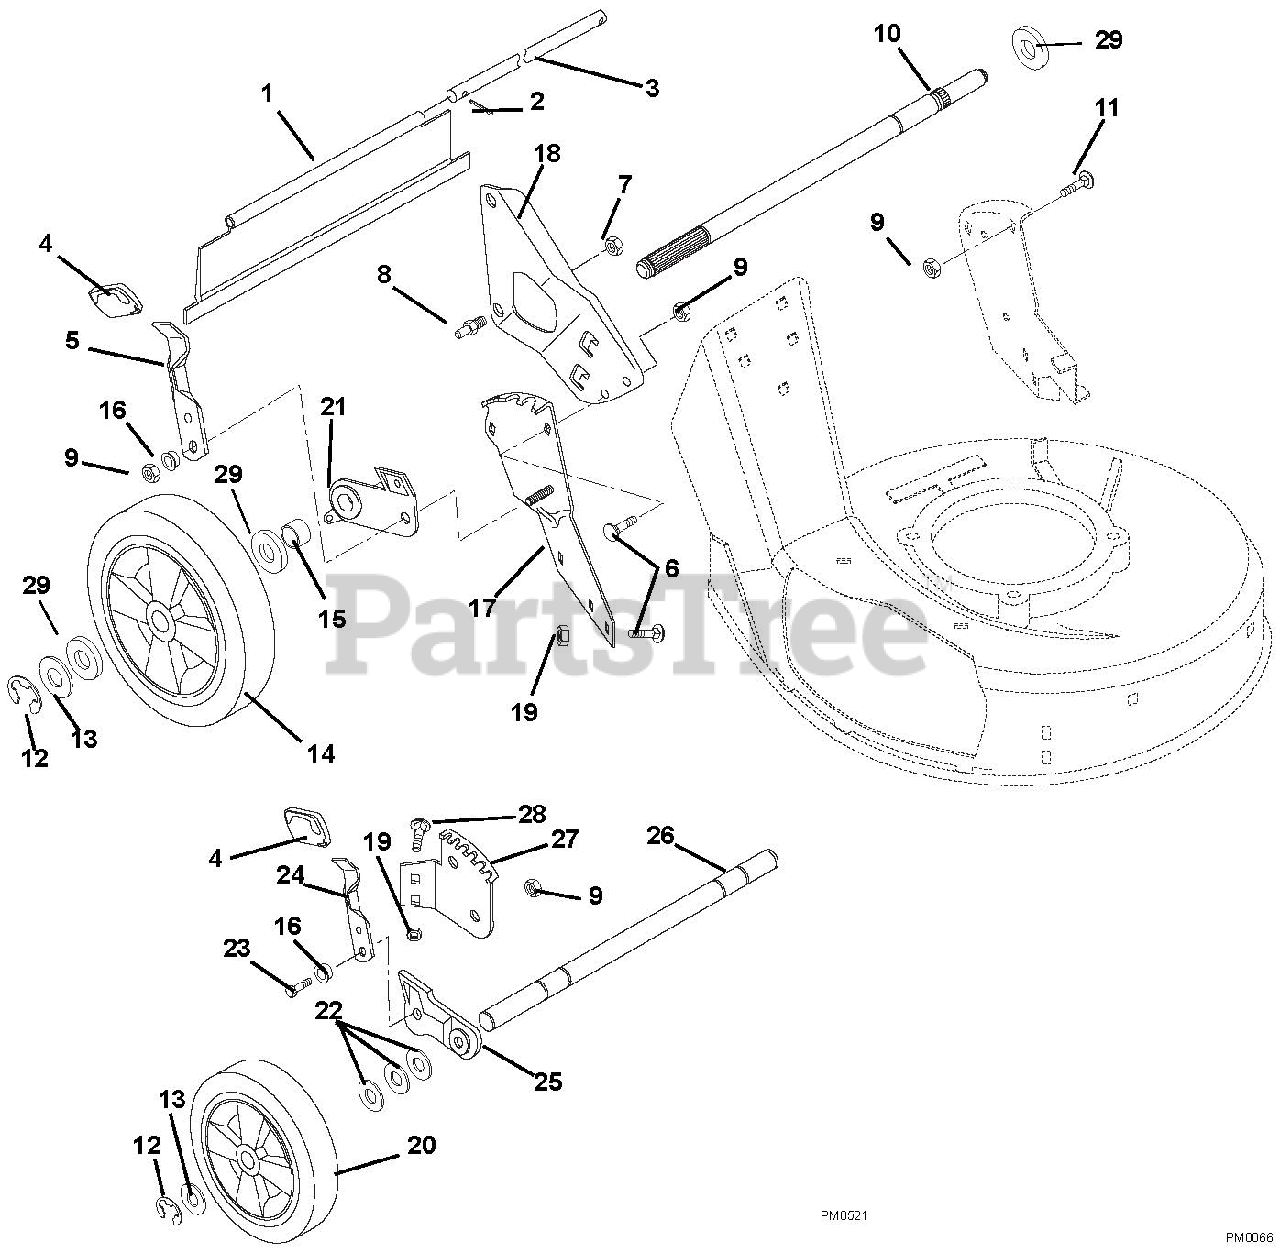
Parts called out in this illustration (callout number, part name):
1	REAR PROTECTIVE GUARD, S.P.
2	@PIN-CTR .06X.50 EXTPRSQCT YWZ
3	ROD
5	LEVER, HEIGHT ADJUSTMENT
6	@BLT-RHDSSQNK .31-18X.62 G5YZ
7	@NUT-LK-CTR .38-16 YWZC
8	HANDLEBAR STUD
9	@NUT-LK-TOP-FLG .31-18 YWZC
10	REAR AXLE,5/8 DIA
10	REAR AXLE-PUSH MOWER MM
11	BLT-RDHDSQNK .31-18X1.0 SHTYZ
12	RG-RTNG-EXT .500X.042 (E)
13	WSHR-FL-STL .505X.880X.072 YWZ
14	WHL, LH 10.50"
14	WHL, RH 10.50"
14	10 1/2 TIRE SKIN
14	TIRE, REAR 10X1.75 #6 GRAY
15	SPACER TUBE, SELF PROPEL
15	SPACER TUBE PUSH RH
16	BSHG-FLG .32X.500X.344X.880
17	QUADRANT, REAR LH
17	QUADRANT, REAR RH
18	RH HANDLEBAR MTG. BRKT
18	LH HANDLEBAR MTG. BRKT
19	@NUT-LK-TOP-FLG .31-18 YWZC
20	WHL 7.50" .50 BORE, 1.50 HUB
21	REAR ADJUSTMENT BRACKET L.H.
21	REAR BRACKET & BEARING ASSY RH
22	WSHR-FL-STL .52X.827X.062 YWZC
23	@BLT-HEX .31-18X1.00 GR5 YWZC
24	FRONT HEIGHT ADJUSTMENT LEVER
25	LEFT ADJUSTOR BRACKET ASSEMBLY
25	RIGHT ADJUSTOR BRACKET ASSEMBL
26	FRONT AXLE
27	FRONT QUADRANT, LH
27	FRONT QUADRANT, RH
28	@BLT-RDHDSQNK .31-18X.50 G5YZ
29	SPACER .531 X 1.00 X .225
